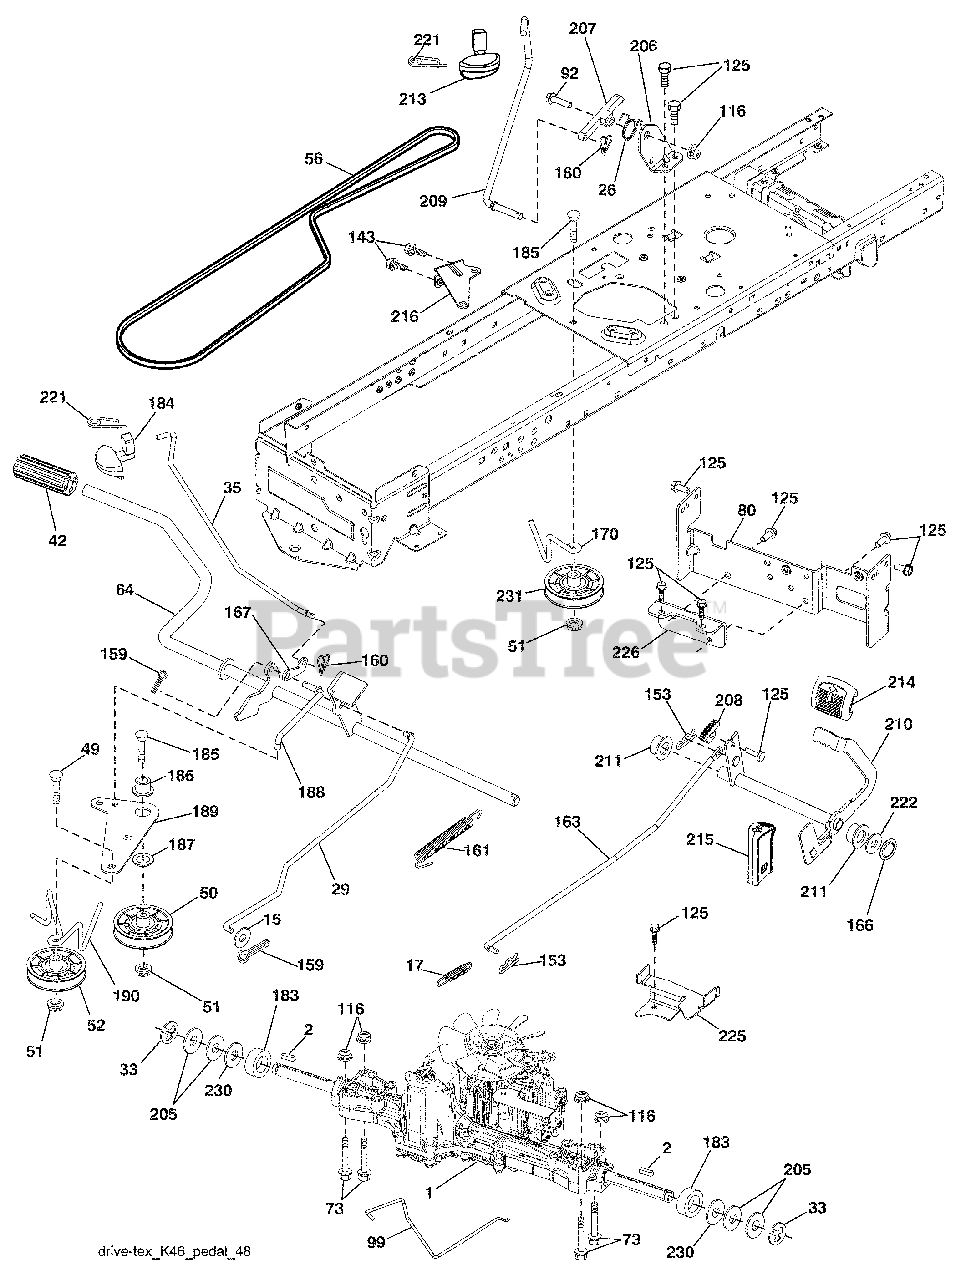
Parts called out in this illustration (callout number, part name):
1	Transaxle, Tufftorq K46BT
2	Key Square
15	Washer 13/32 x 13/16 x 16 Ga.
17	Spring, Brake
26	Spring Return Cruise
29	Rod, Brake
35	Rod, Brake, Park
42	Cover, Foot Pedal
50	Pulley Idler Flat
51	Lock Nut 3/8-16
52	Idler V-Groove 910" Offset
56	V-Belt, Drive
64	Shaft Asm. Pedal Brake Control
73	Bolt Hex 5/16-18 Gr. 5
80	Strap Torque
92	Bolt Fin Hex 5/16-18 unc x 1.25
99	Rod Spring Bypass
116	Nut Lock Hex Flange 5/16-18
125	Screw 5/16-18 x 3/4
143	Screw 5/16-18 x 1/2
153	Retainer Spring 1"
159	Pin Cotter 1/8 x 3/4
160	Retainer Clip
161	Spring, Return, Clutch
163	Rod Control
166	Nut Push
167	Latch Brake Parking
170	Keeper V-Idler
183	Spacer Axle
184	Handle Parking Brake
186	Spacer Retainer
187	Washer
188	Link Clutch Ground Drive
189	Bellcrank Ground Drive
190	Keeper Bellcrank Ground Drive
205	Washer 25/32 x 1-5/8 x 16 Ga.
206	Bracket Mount Latch Cruise
207	Latch Control Cruise
208	Gear Sector Control Cruise
209	Rod Control Cruise
210	Rocker Asm. Pedal Control
211	Bearing Nylon
213	Knob Control Cruise
214	Pedal Forward Pad
215	Pedal Reverse
216	Bracket Pulley Idler
221	Retainer Spring Clip Handle
222	Washer 21/32 x 1-1/4 10 Ga.
225	Keeper Belt Transaxle
226	Bracket Mount Torque
230	Washer Harden .793 x 1.637 x 060
231	Idler V-Groove 1.688" Offset
